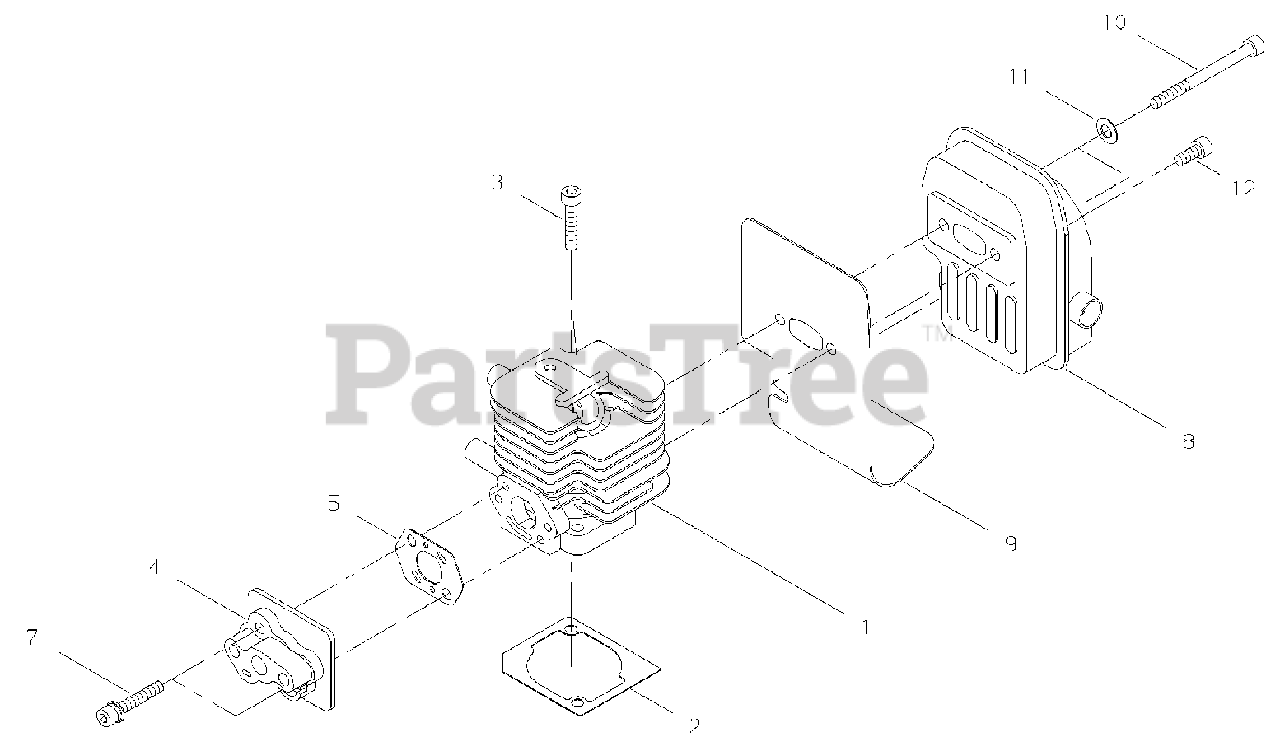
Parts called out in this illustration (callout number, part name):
1-1	CYLINDER
2	GASKET, CYLINDER
3	SCREW - 5X25
4	INSULATOR
5	GASKET
7	SCREW - 5X30
8	MUFFLER
9	SHIELD, EXHAUST
10	SCREW - 5X50
11	WASHER - 5
12	SCREW - 5X12
